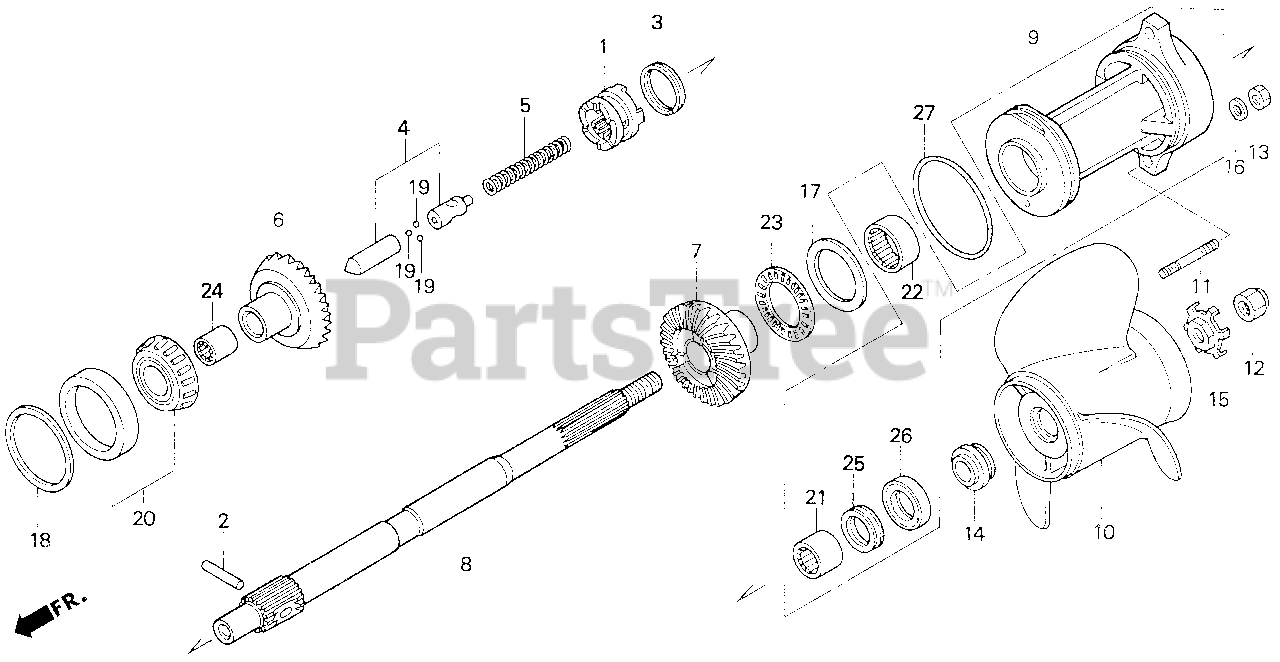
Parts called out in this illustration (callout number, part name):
1	SHIFTER, CLUTCH
2	PIN, SHIFTER
3	RING, CROSS PIN
4	SLIDER, SHIFT
5	SPRING, SHIFT
6	GEAR, BEVEL (F)
7	GEAR, BEVEL (R)
8	SHAFT, PROPELLER
9	HOLDER ASSY., PROPELLER SHAFT
10	PROPELLER, THREE-BLADE
10	PROPELLER, THREE-BLADE (13X18)
10	PROPELLER, THREE-BLADE (14X11)
10	PROPELLER, THREE-BLADE (14X13)
10	PROPELLER, THREE (13-1/4X17)
10	PROPELLER, THREE-BLADE (13X19)
11	BOLT, STUD
12	NUT, PROPELLER HUB
14	WASHER, PROPELLER THRUST
15	WASHER, TAB
16	WASHER, PLAIN
17	WASHER, THRUST
18	SHIM, BEVEL GEAR (F)
19	BALL, STEEL
20	BEARING, TAPERED ROLLER
21	BEARING, NEEDLE
22	BEARING, ROLLER
23	BEARING, THRUST
24	BEARING, ROLLER
25	SEAL, WATER (INNER)
26	SEAL, WATER (OUTER)
